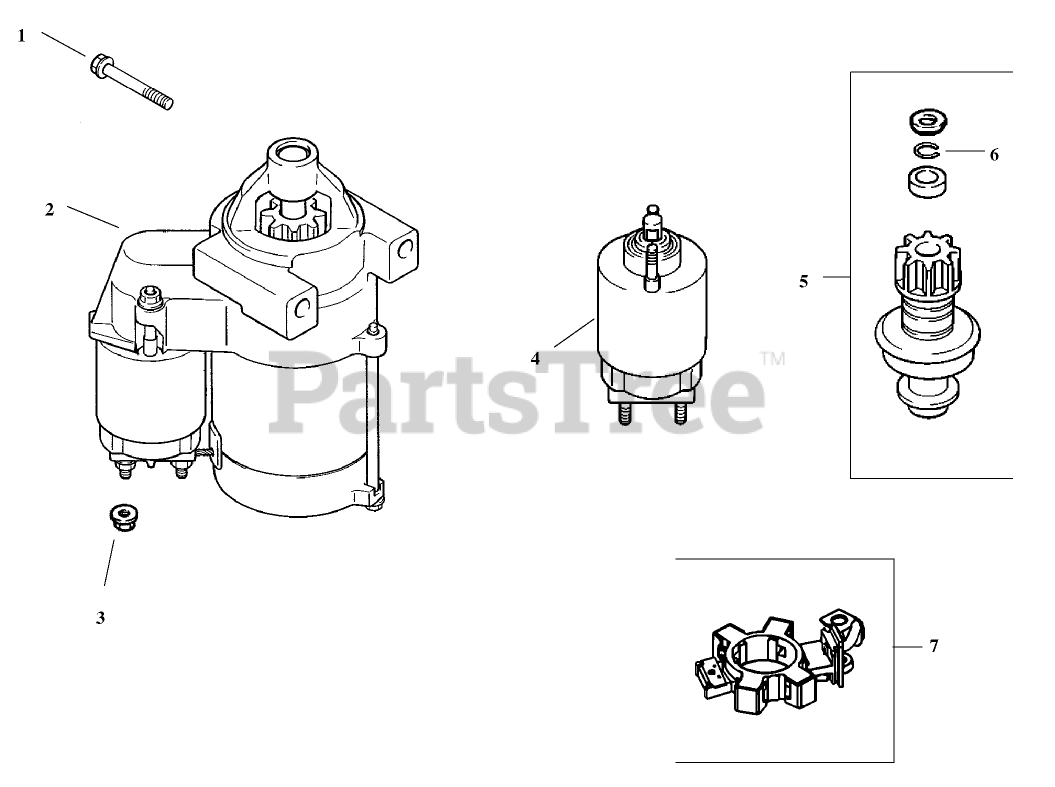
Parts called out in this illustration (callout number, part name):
1	SCREW-FLG (M8X1.25X80)
2	Starter, solenoid shift (Includes 3-7)
3	NUT-FLANGE (M8X1.25)
4	Solenoid Kit
5	Kit, drive (Includes 6)
6	RING-RETAINING
7	BRUSH HOLDER KIT
